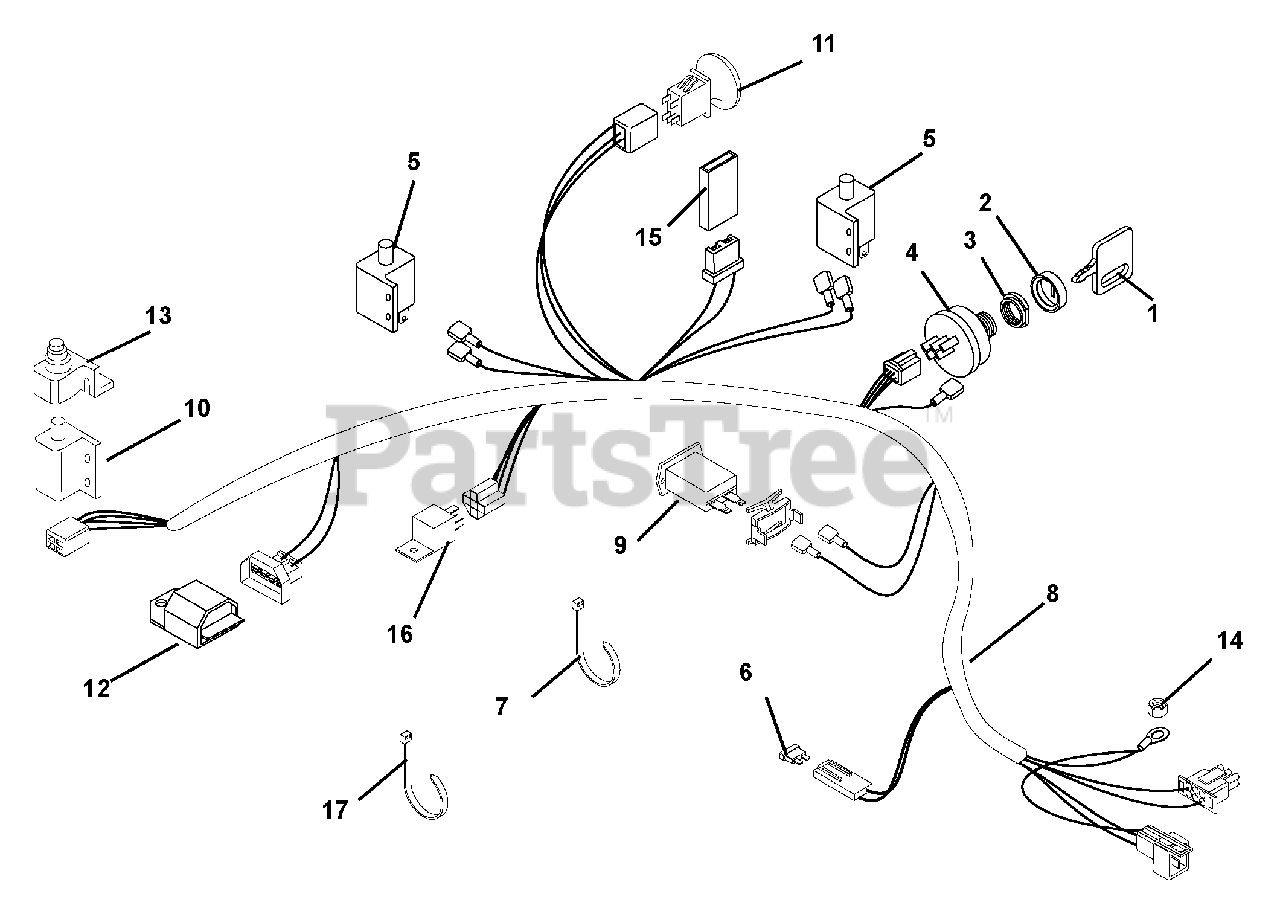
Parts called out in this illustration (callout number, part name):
1	KEY -W/CAP
2	CAP - IGNITION SWITCH
3	NUT- PANEL .562-24 GRECO
4	KEY SWITCH
5	SWITCH- DOUBLE POLE N.O./N.O.
6	FUSE-25 AMP ATC TYPE
7	CABLE TIE LG 5-1/2
8	HARNESS-WIRE HYDRO RECOIL-ERGO
9	HOURMETER-QUARTZ 80VDCMAX
10	SWITCH,INTERLOCK
11	SWITCH - PTO - NMIR
12	MODULE,INTERLOCK,RECOIL, 1201
13	BOOT, RUBBER
14	@NUT-LK-TOP-FLG .31-18 YWZC
15	DIODE, CONNECTOR SHELL
16	RELAY
17	TIE WRAP
